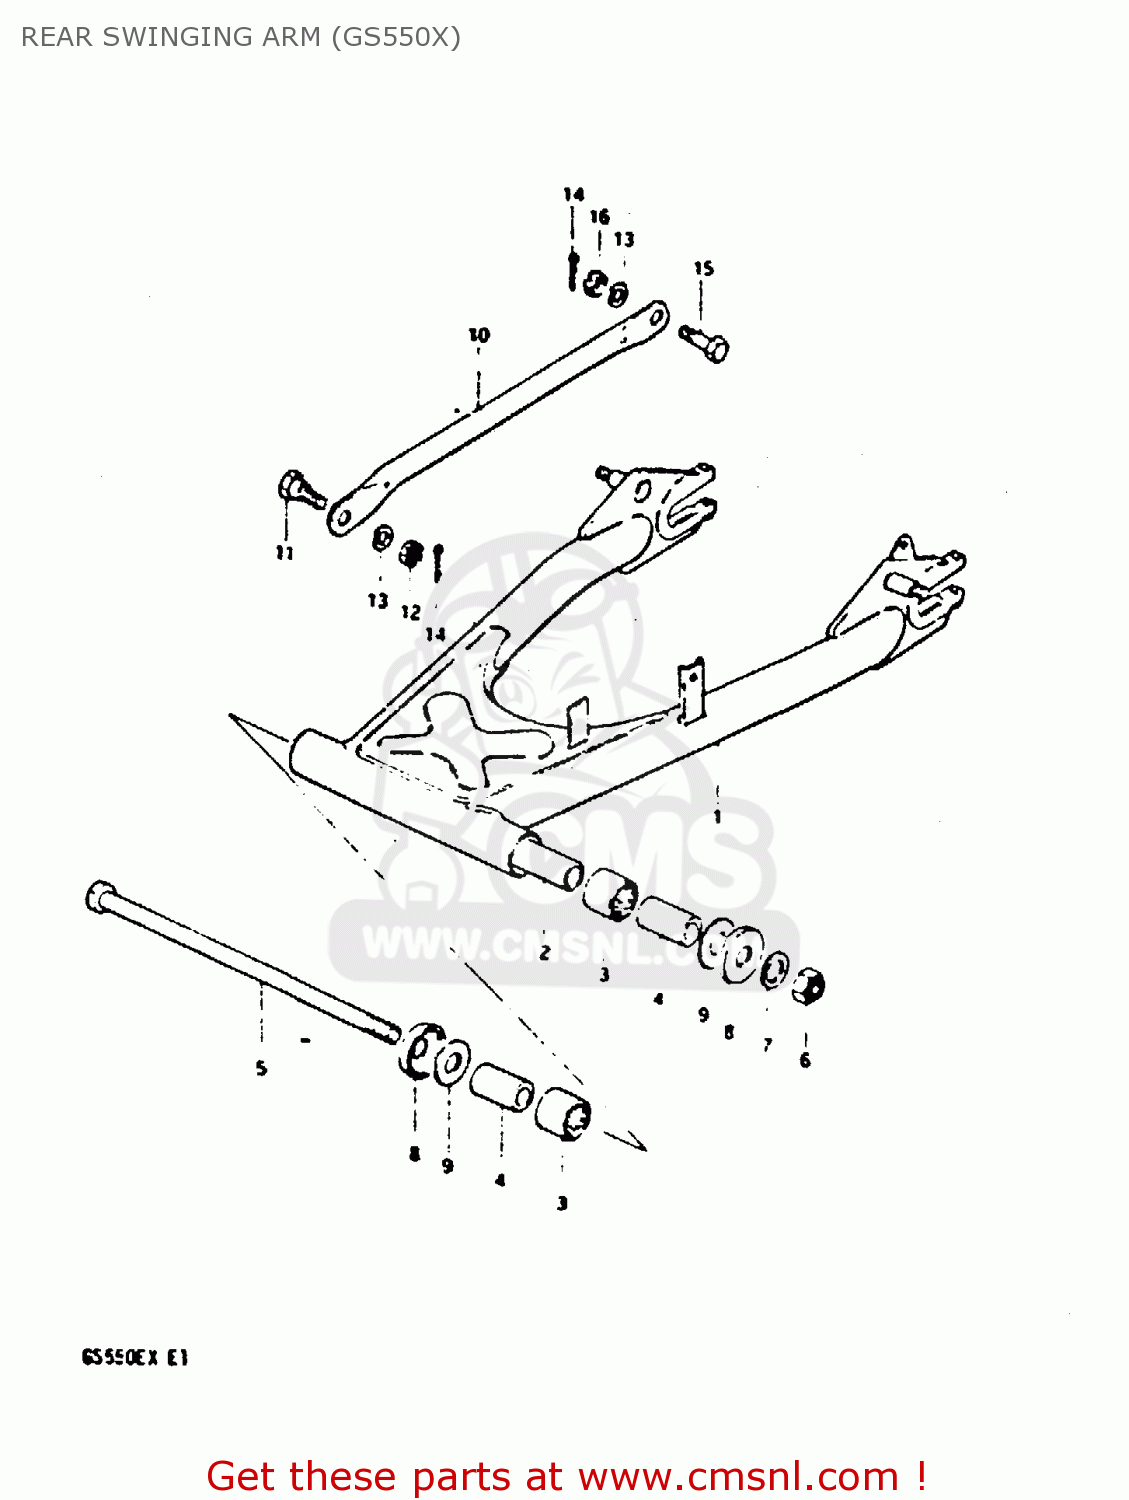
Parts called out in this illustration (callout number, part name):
1	SWING ARM ASSEMBLY,REAR
2	SPACER,RR SWGARM PIVOT CTR
3	BEARING(22X29X30)
4	SPACER,RR SWGARM PIVOT
5	SHAFT,REAR SWING ARM
6	NUT 14MM
7	WASHER
8	CVR,RR SWGARM DUST SEAL(OD:40)
9	WASHER(14.2X34X1)
10	TORQUE LINK,REAR
11	BOLT(10X24.5)
12	NUT
13	LOCK WASHER
14	PIN 20X20
15	BOLT(10X31)
16	NUT
